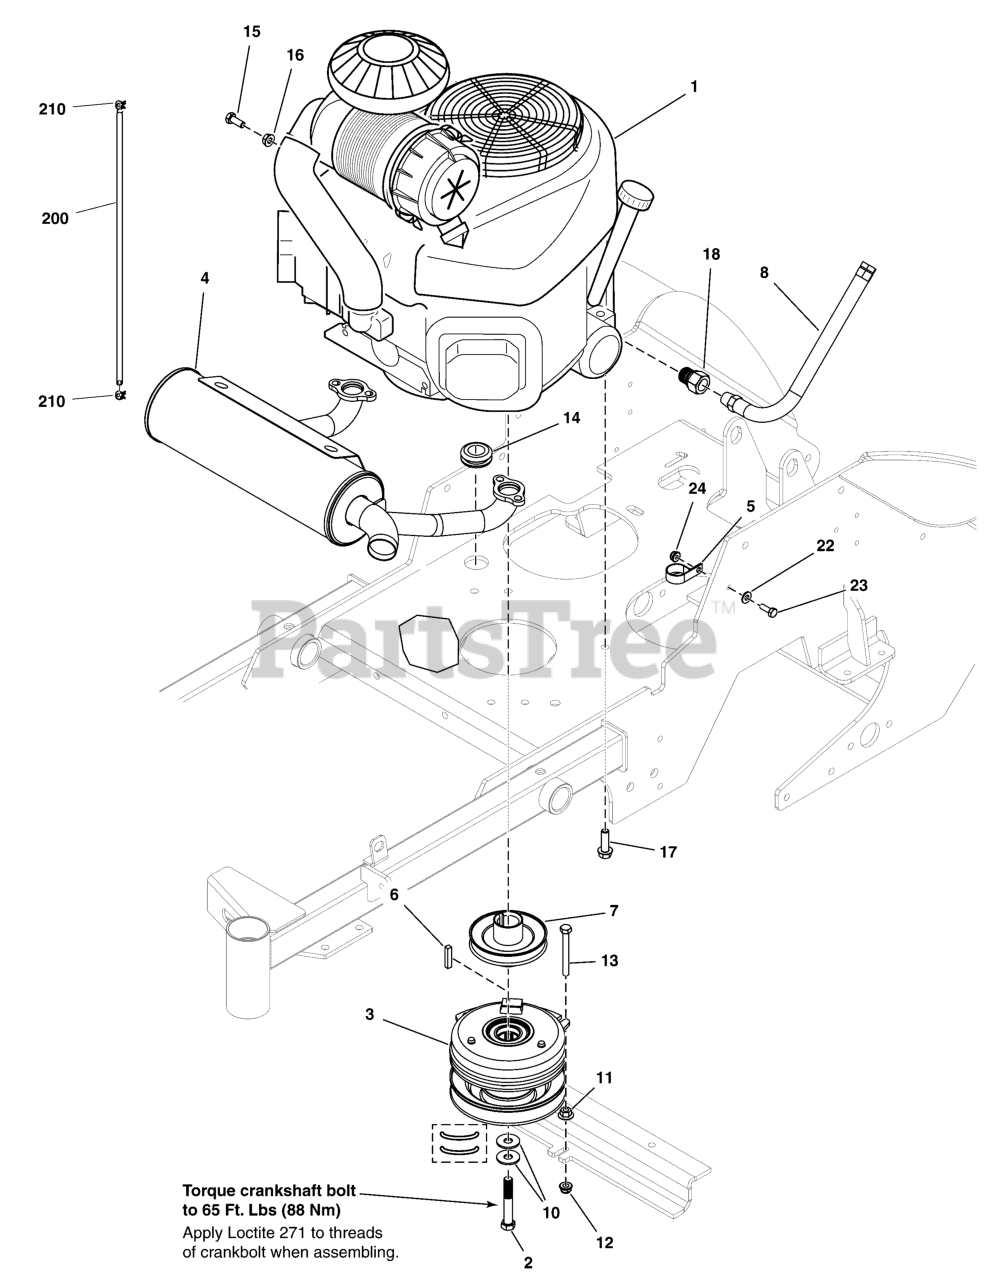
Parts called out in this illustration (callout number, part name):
2	BOLT, CRANKSHAFT, 7/16 X 2-3/4, PATCH, CZ
3	CLUTCH, WARNER, 125 FTLBS - 1.13"
4	MUFFLER 15-19HP KAWI
5	CLAMP, VINYL INSULATED, 1.00
6	KEY, 1/4" SQ. X 1-1/4
7	PULLEY, CRANKSHAFT, 1.1255 ID X 4.00 OD
8	HOSE, OIL DRAIN
9	TIE,SELF-LOCKING, 24"
10	BELLEVILLE WASHER, 1.1875 X .442 X .098
12	NUT, 5/16-18 HEX NYLOCK FLANGE NUT
14	GROMMET, 7/8"ID, 1/4" THICK STK
15	BOLT, M8-1.25 X 16MM GD8.8
16	NUT, M8-1.25 Hex Serrated Flange
17	BOLT, 3/8-16X1-1/4 SF, GD8, PHOS, SER HD
18	ADAPTER, Oil Drain
22	WASHER, 1/4 SAE
23	BOLT, 1/4"-20 X 3/4" GD5 YZ
24	NUT, 1/4-20 Hex Nylock Flange
200	HOSE, 1/4" FUEL, 15.50"
210	CLAMP, Hose
